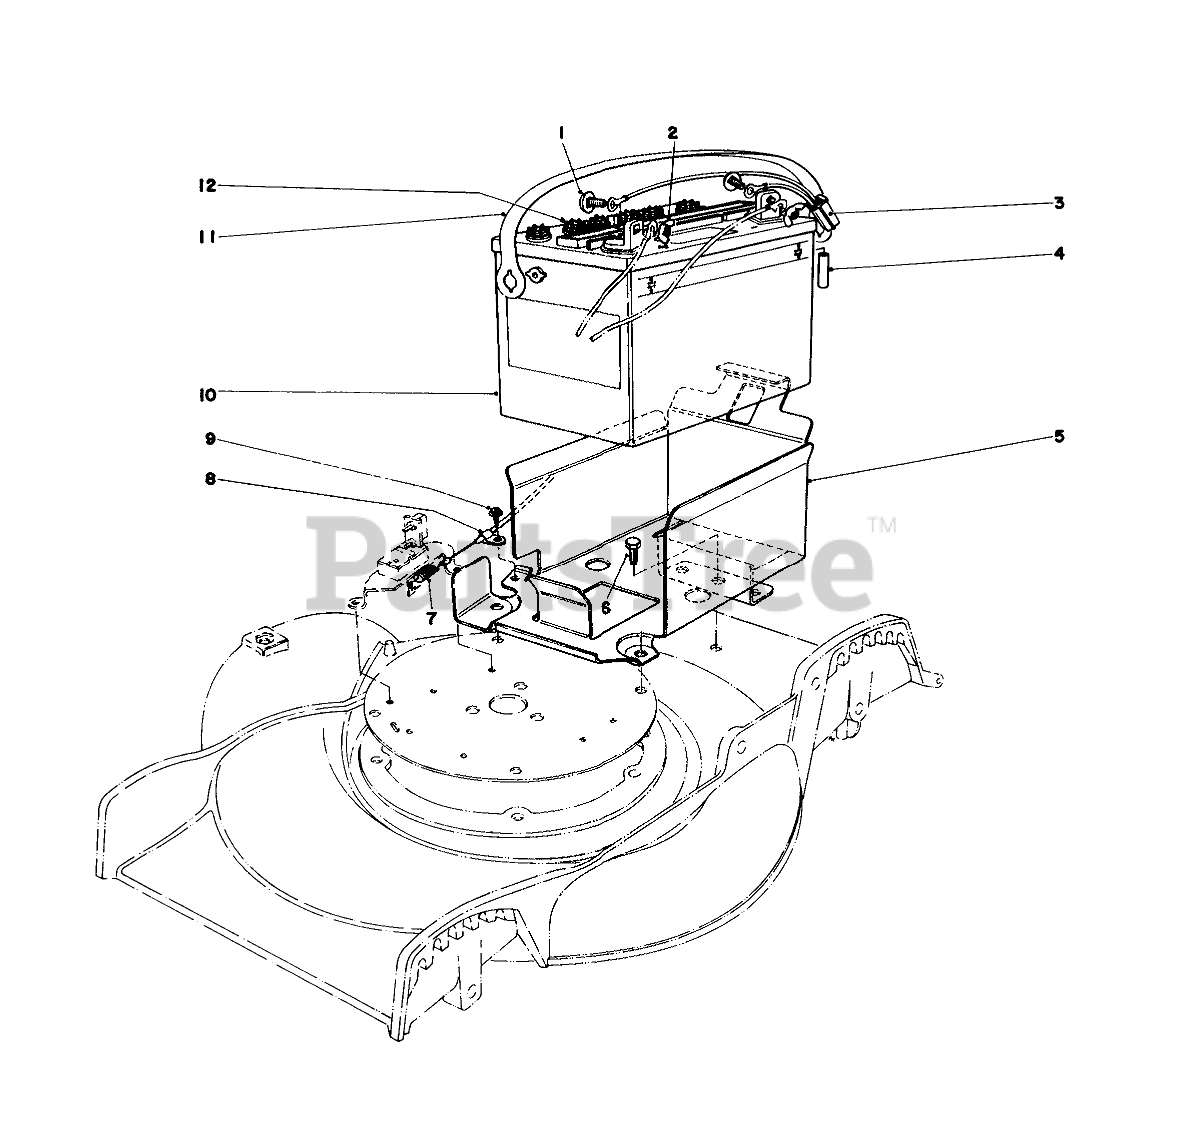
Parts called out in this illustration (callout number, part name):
1	Bolt-Carriage
2	NUT-WING
3	Battery Harness
4	Vent Tube
5	Battery Holder
6	SCREW-HWHTF
7	Control Cable Assembly
8	Clamp
9	SCREW-HWHTF
10	Battery (Incl. Ref. #1-3)
11	Carrying Strap
12	Vent Cap
